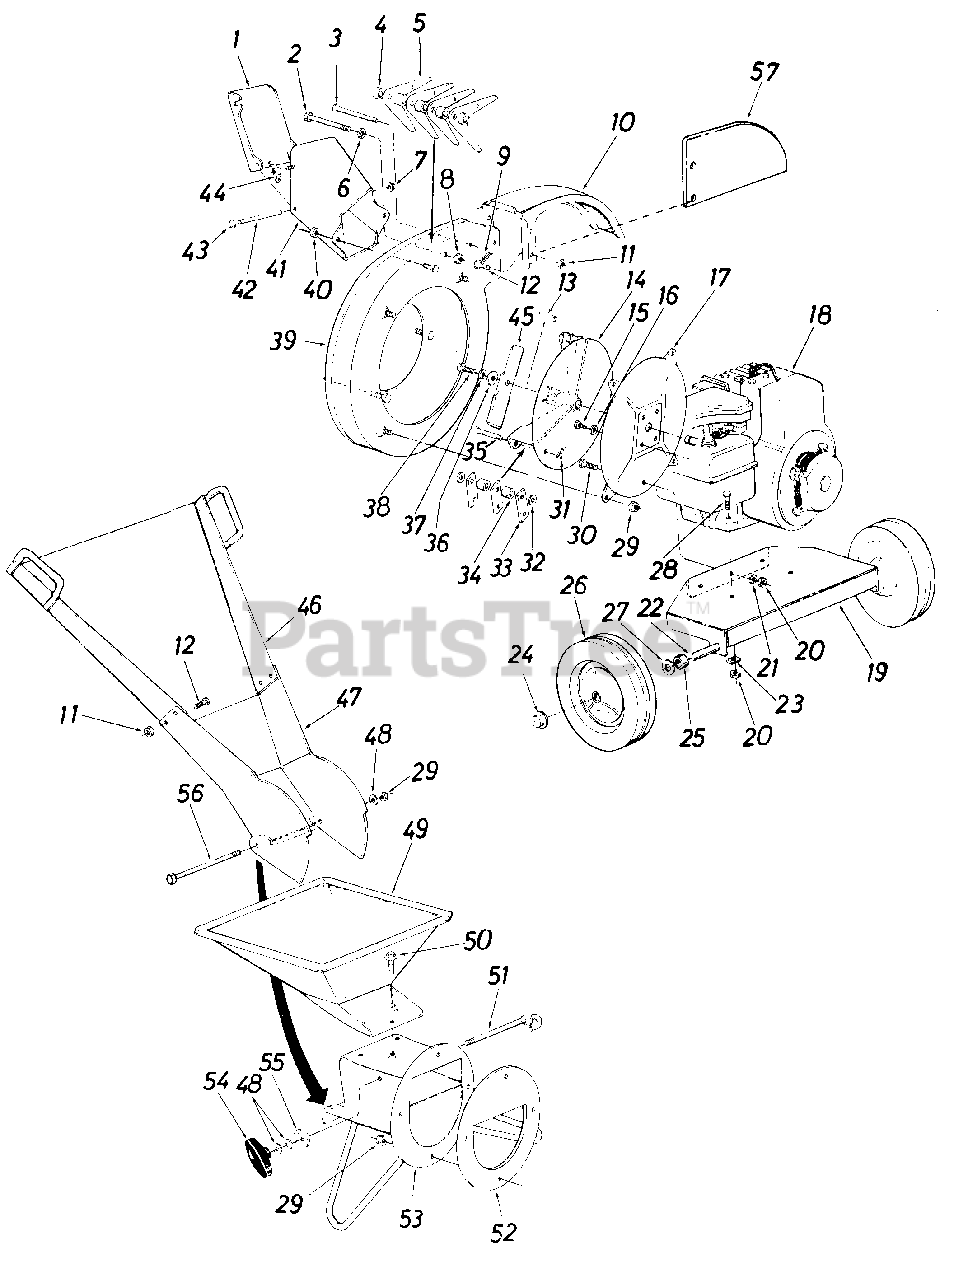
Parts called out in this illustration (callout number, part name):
1	Door Chip It
2	Hex Bolt 1/2-20 x 4.50" Lg.
3	Clevis Pin
4	Flail Spacer 7/32" Lg.
5	Cutting Finger
6	L.-Wash. 1/2" Scr.
7	Palnut 3/16" Dia.
8	Hex Jam Nut 1/2-20 Thd.
9	Cotter Pin 3/32" Dia. x 3/4" Lg.
10	Chute Deflector
11	L.-Nut 1/4-20 Thd.
12	Hex Bolt 1/4-20 x .50" Lg.
13	Sq. Key 1/4" x 2.00" Lg.
14	Impeller Assembly
15	Hex Bolt 5/16-24 x 3/4" Lg.
16	L-Wash. 5/16" Scr.
17	Hopper to Engine Mtg. Plate
18	Engine
19	Engine Mounting Plate
20	Hex Nut 5/16-24 Thd.
21	L.-Wash. 5/16" Scr.
22	Shaft
23	Special L.-Wash. 5/16" I.D.
24	Push Cap
25	Spacer
26	Wheel Ass'y.-Comp.
27	Fl-Wash. .50" I.D.
28	Hex Bolt 5/16-24 x 1.50"
29	Elastic Stopnut 5/16-18 Thd.
30	Hex Bolt 5/16-24 x .62" Lg.
31	Cotter Pin 1/8" Dia. x 1.00" Lg.
32	Fl-Wash. .531" I.D. x 937 O.D. x .09
33	Flail
34	Flail Spacer 23/32" Lg.
35	Clevis Pin .50" Dia. x 3.0" Lg.
36	Fl.-Wash. .406" I.D. x 1.25" O.D. Hdn.
37	L-Wash. 3/8" Scr. H.D.
38	Hex Bolt 3/8-24 x 2.00" Lg. H .T.
41	Upper Guide Extension Ass'y.
42	Hinge Pin
43	Palnut 3/16" Dia.
44	Wing Nut Elastic 1/4-20 Thd.
47	Guide Extension
48	Fl.-Wash. 5/16" Scr.
49	Hopper Assembly
50	Hex Wash. Hd. Self-Tap Scr. 5/16-18 x .50" Lg.
51	Clamp Rod Assembly
52	Back-Up Plate
53	Inlet Guide Assembly
54	Knob Ass'y.
55	Stop Washer
56	Hex Bolt 5/16-18 x 8.38" Lg.
57	Deflector Side Plate
